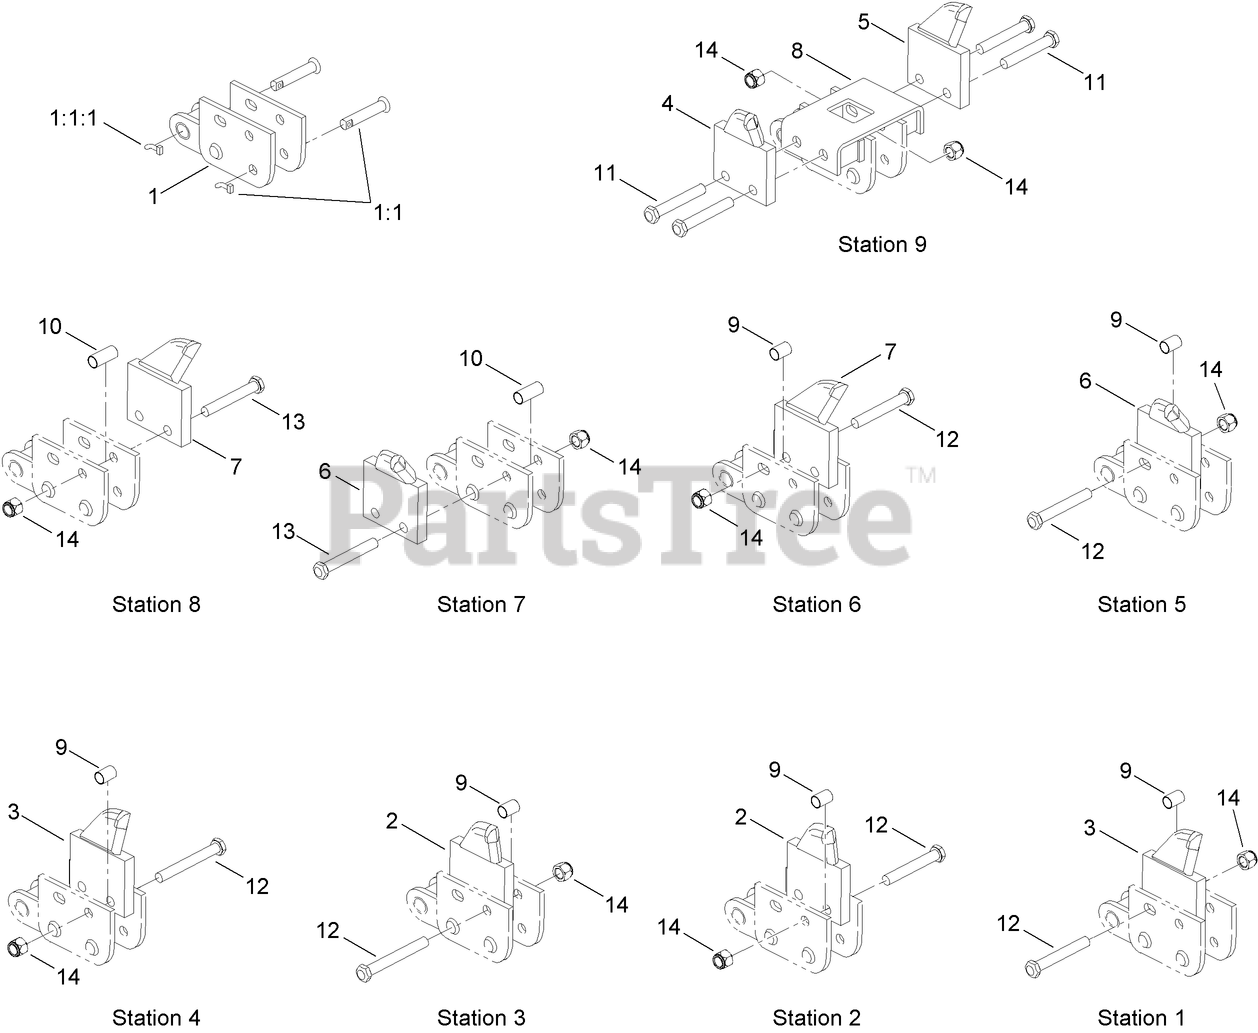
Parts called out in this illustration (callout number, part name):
1	CHAIN REPAIR LINK ASM
1:1	NOTCHED PIN AND KEEPER ASM
1:1:1	PIN-KEEPER
2	TOOTH-TERMINATOR, RH CENTER
3	TOOTH-TERMINATOR, LH CENTER
4	TOOTH-TERMINATOR, RH
5	TOOTH-TERMINATOR, LH
6	TOOTH-TERMINATOR, RH
7	TOOTH-TERMINATOR, LH
8	SADDLE-TOOTH SPREADER
9	SPACER-TUBE, INSIDE ADAPTER
10	SPACER-TUBE, OUTSIDE MOUNT
11	BOLT-HH
12	BOLT-HH
13	BOLT-HH
14	NUT-LOCK
